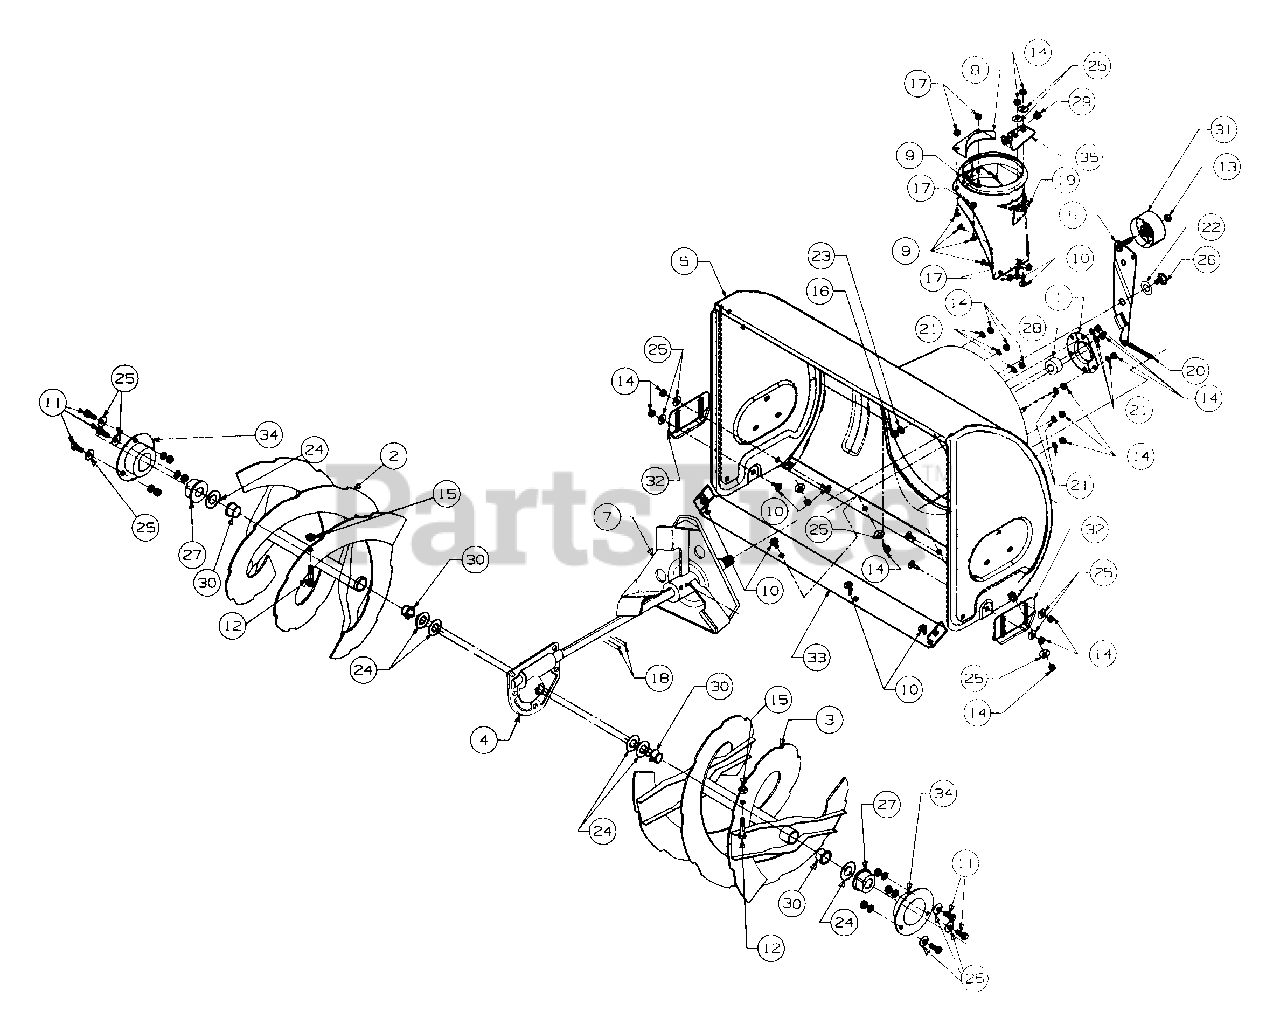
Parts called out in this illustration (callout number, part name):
1	Housing - Bearing
2	Spiral Assembly - L.H. 24"
2	Spiral Assembly - L.H. 28"
3	Spiral Assembly - R.H. 24"
3	Spiral Assembly - R.H. 28"
4	Gear Assembly 24"
4	Gear Assembly 28"
7	Impeller Assembly
9	Screw - Carriage
10	Screw - Carriage
11	Screw - Hex
12	Shear Bolt
13	Nut - Hex Lock
14	Nut - Hex
15	Nut - Hex
16	Nut - Hex
17	Nut - Hex Lock
18	Pin - Spring
19	Adapter - Chute
20	Spring
21	Washer - Lock
22	Washer - Flat
23	Washer - Lock
24	Washer - Flat
25	Washer - Bell
26	Screw - Shoulder
27	Bearing - Flange
28	Bearing - Ball
29	Bushing - Plastic
30	Bushing - Flange
31	Idler - Flat
33	Shave Plate 24"
33	Shave Plate 28"
34	Housing - Bearing
35	Bracket - Chute Crank
